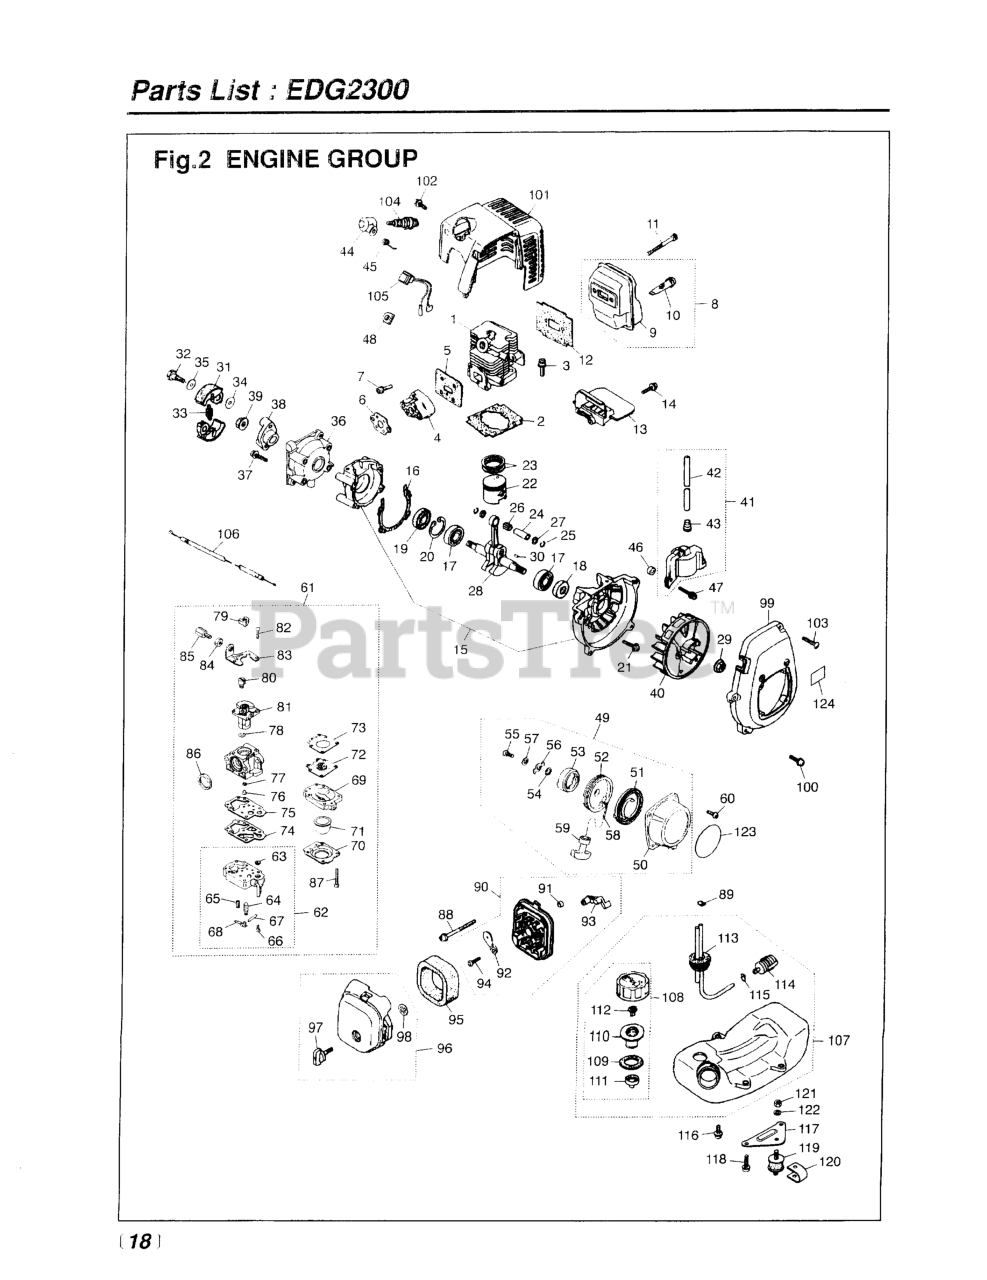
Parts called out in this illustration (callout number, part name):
1	CYLINDER
3	BOLT, M5 X 22
8	MUFFLER ASSY
9	MUFFLER
10	ARRESTER (RPLS 5850-15140)
11	BOLT, M5 x 50
12	GASKET, MUFFLER
15	CRANKCASE COMP.
17	BEARING
18	SEAL, OIL (RPLS 1100-21210)
19	SEAL, OIL (RPLS 1140-21220)
20	RING, SNAP, M28 x 1.2
21	BOLT, M5 X 30
22	PISTON (REPLACES 1140-41110)
23	RING, PISTON (RPLS 1850-41210)
24	PIN, PISTON 5x8x26
25	RING, SNAP (RPLS 1101-41320)
27	WASHER
28	CRANKSHAFT (RPLS -42000)
30	KEY
31	SHOE, CLUTCH (RPLS -51110)
32	BOLT
33	SPRING, CLUTCH (RPLS-51220)
34	WASHER, FLAT (USE 182303)
36	CASE, CLUTCH (USE 1140-21162)
38	PLATE, CLUTCH
41	COIL ASSY (RPLS 5500-71200)
42	CORD
43	CAP
45	SPRING
46	SPACER (RPLS -71260)
47	BOLT
48	GROMMET
50	CASE, RECOIL
51	SPRING, SPIRAL
54	WASHER
55	SCREW
56	RETAINER (RPLS 1861-75161)
57	WASHER
58	ROPE
61	CARBURETOR
62	BODY, PUMP
64	VALVE, INLET
65	SPRING, METERING LEVER
66	SCREW, METERING LEVER PIN
67	PIN, METERING LEVER
68	LEVER
69	BODY, PURGE
71	PUMP, PRIMING
72	DIAPHRAGM (USE 4810-81260)
73	GASKET, DIAPHRAGM
74	DIAPHRAGM
75	GASKET, PUMP
76	JET
77	RING, O
78	RING
79	WASHER
80	SWIVEL
82	SCREW
84	NUT, CABLE ADJUSTER
85	SCREW, CABLE ADJUSTER
86	RING, PACKING
87	SCREW
89	CLIP
90	BODY-A (RPLS -82101)
91	SLEEVE
92	PLATE, CHOKE (RPLS-82130)
93	LEVER, CHOKE
94	SCREW (REPLACES 50030272)
95	ELEMENT
97	KNOB (RPLS -82220)
98	RING
101	COVER, ENGINE(USE-32101)
102	SCREW, M5 x 12
103	SCREW, HOUSING
105	SWITCH, STOP
109	PACKING
111	HOLDER, CAP
112	VALVE (NLA WHEN OUT)
113	PIPE COMPLETE
114	FILTER (RPLS 1850-85300)
115	CLIP (REPLACES 2841-31280)
116	SCREW
119	JOINT
120	BAND
121	NUT (M5X0.8)
122	WASHER, SPRING M4 x 1.3
123	LABEL, RECOIL
